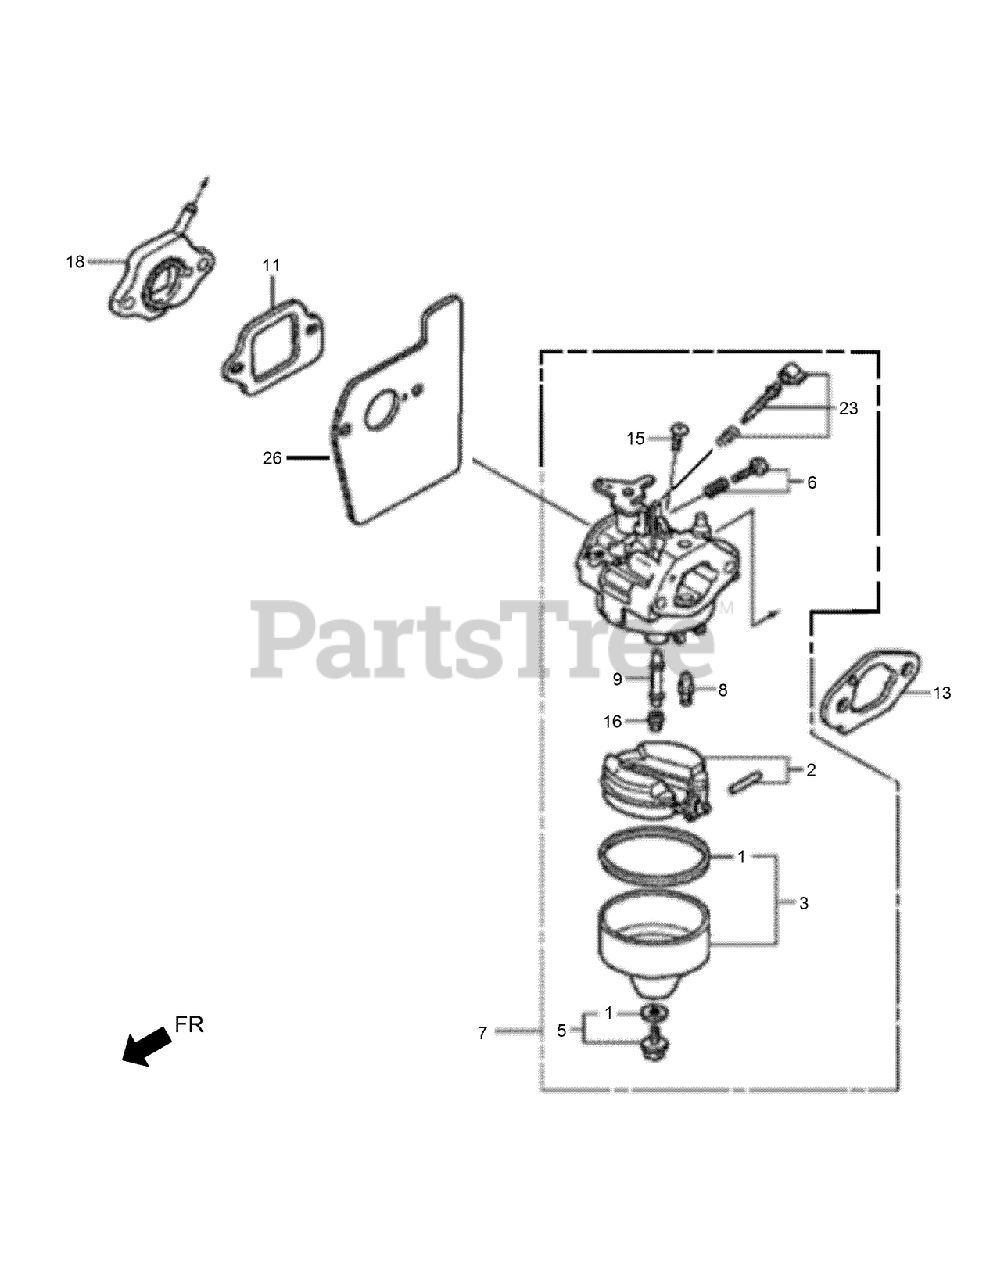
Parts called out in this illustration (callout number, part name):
1	PACKING SET
2	FLOAT SET
3	CHAMBER SET-FLOAT
5	SCREW SET
6	SCREW SET
7	CARBURETOR ASM (BB62Y C)
8	VALVE-FLOAT
9	NOZZLE-MAIN (BB62W C)
11	PACKING-INSULATOR
13	PACKING-CARBURETOR
15	SCREW-PAN-5X6
16	JET-MAIN NO. 62
16	JET-MAIN NO. 65
18	CARBURETOR INSULATOR ASM
23	SCREW SET
26	GUIDE-AIR
